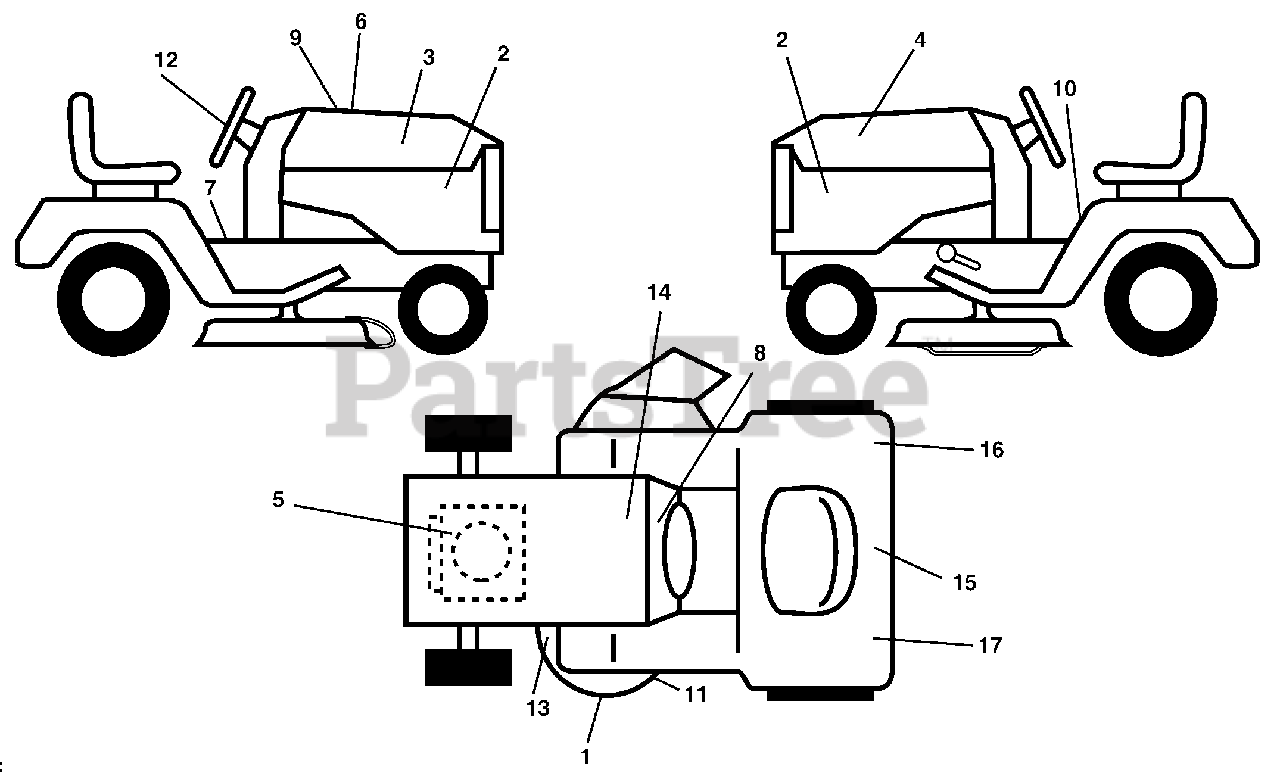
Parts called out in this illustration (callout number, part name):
1	Decal Deck Hvy Duty
2	Decal Panel Side
3	Decal Hood RH
4	Decal Hood LH
5	Decal HP Engine
6	Decal Hood Cust. Resp.
7	Decal Operator
8	Decal Dash
9	Decal Replacement
10	Decal Fender Danger
11	Decal V-Belt Sch.
12	Decal Wheel Steering
13	Decal Deck Caution
14	Decal Bat Dan/Psn
15	Decal Fender
16	Decal, Refl ector RH
17	Decal, Refl ector LH
